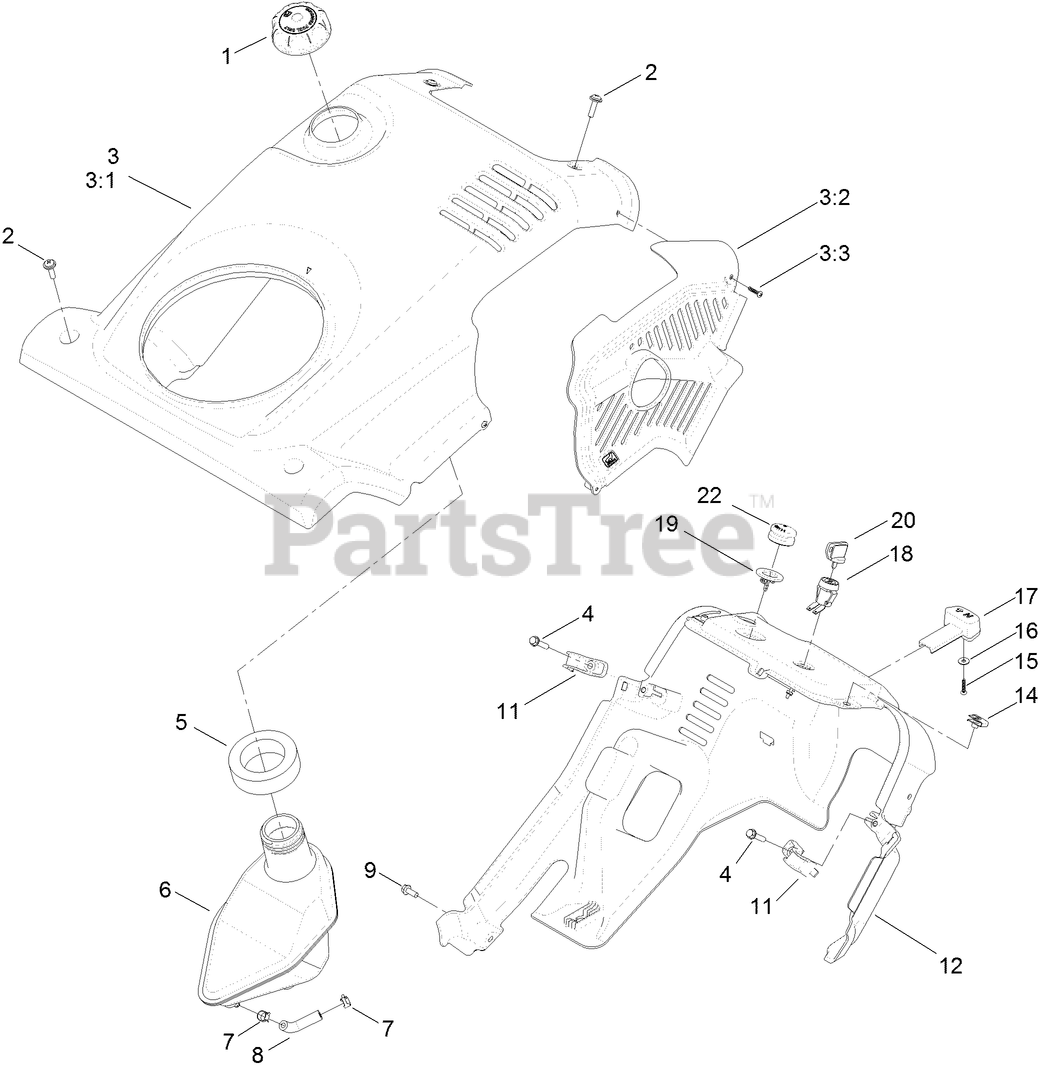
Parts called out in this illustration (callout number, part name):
2	SCREW-PPH
3	SHROUD ASM
3:1	SHROUD
3:2	BAFFLE-EXHAUST
3:3	SCREW-PPH
4	SCREW-PLASTITE
5	SEAL-TANK
6	TANK-FUEL, GAS
7	CLAMP-HOSE
8	HOSE-FUEL
9	SCREW-HWH
11	CLIP-SHROUD
12	SHROUD-LOWER
15	SCREW-PPH
16	WASHER-PLAIN
17	KNOB-CHOKE
18	SWITCH
19	BODY-PRIMER
20	KEY-IGNITION
22	BULB-PRIMER
